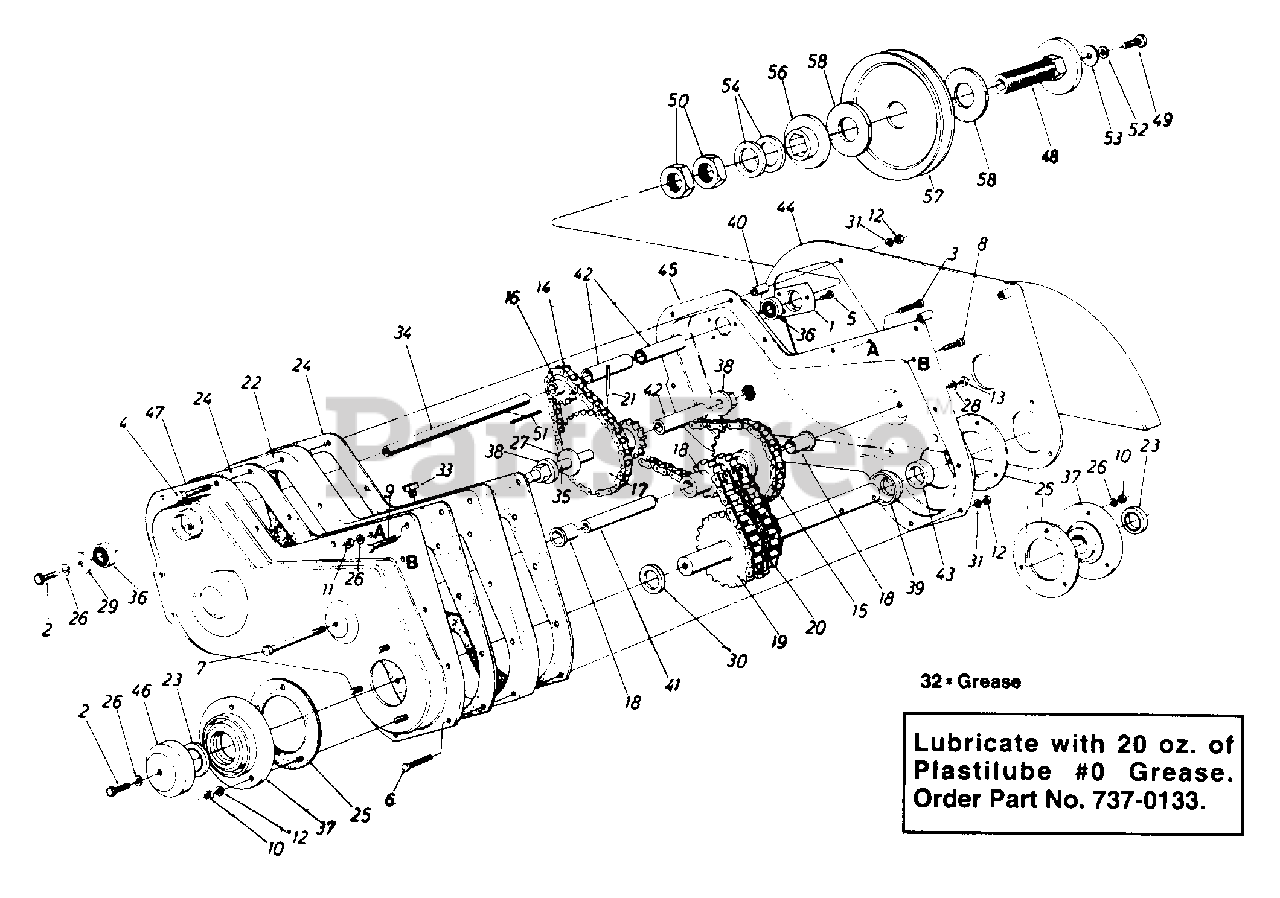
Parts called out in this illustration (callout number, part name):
1	Bearing Housing 1-3/8" Dia.
2	Hex Bolt 5/16-18 x .88"
3	Hex Bolt 5/16-18 x 1.5" Lg.
4	Hex Bolt 1/4-20 x 2.75" Lg.
5	Hex S-Tap Scr. 1/4-20 x .5" Lg.
6	Hex Bolt 1/4-20 x 1.5" Lg.
7	Hex Bolt 3/8-16 x 4.5" Lg.
8	Hex Scr. 1/4-20 x 1.5" Lg.
9	Hex TT-Tap Scr. 5/16-18 x 1.75"
10	Hex L-Nut 5/16-18 Thd.
11	Hex Nut 5/16-18 Thd.
12	Hex Nut 1/4-20 Thd.
13	Hex Nut 3/8-16 Thd.
14	#41 Chain 1/2" Pitch x 34 Links - Endless
15	#42 Chain 1/2" Pitch x 48 Links - Endless
16	Sprocket 10 Tooth .5" Pitch
17	10 & 28 Teeth Sprocket Ass'y.
18	8-2 & 28 Sprocket Sleeve Ass'y.
19	18-2 Sprocket Shaft Ass'y.
20	#50-2 Chain 5/8" Pitch x 28 Links - Endless
21	Spring Pin Spir. 1/4" Dia. x 1.5" Lg.
22	Spacer Block - Tiller Housing
23	Oil Seal 1-1/4" Dia.
24	Gasket for Tiller Housing
25	Gasket for Brg. Housing
26	L-Wash. 5/16" I.D.
27	Fl-Wash..64" I.D. x 1.24" O.D.
28	L-Wash. 3/8" I.D.- H.D.
29	Fl-Wash..344" I.D. x 1.125"
30	Special Washer
31	L-Wash. 1/4" I.D.
33	Vent Plug
34	Jack Shaft .525" I.D. x 7.78"
35	Sprocket Shaft .63" Dia. x 5"
36	Ball Brg..62" I.D. x 1.38" O.D.
37	Bearing Housing - 1-1/4"
38	Hex Flange Brg.
39	Spacer 1.25" I.D. x 2.0" O.D.
40	Spacer .9" Lg.
41	Spacer 3.44" Lg.
42	Spacer .62" x
43	Spacer .5" Lg.
46	Dust Cap
49	Hex Bolt 5/16-18 x 1.25" Lg. Grade 5
50	Hex Jam Nut 1.0-14 x 28 Thd.
51	Sq. Key 3/16 x 1.5" Lg.
52	L-Wash. 5/16" I.D."
53	Fl-Wash..344" I.D. x 1.125"
54	Bell-Wash. 1.0" I.D. x 2.0"
56	Floating Disc 3-1/4" O.D.
57	5/8 V-Pulley 1.5" I.D. x 6.5"
58	Friction Pad 3-1/4" O.D. x 1-3/8" I.D.
